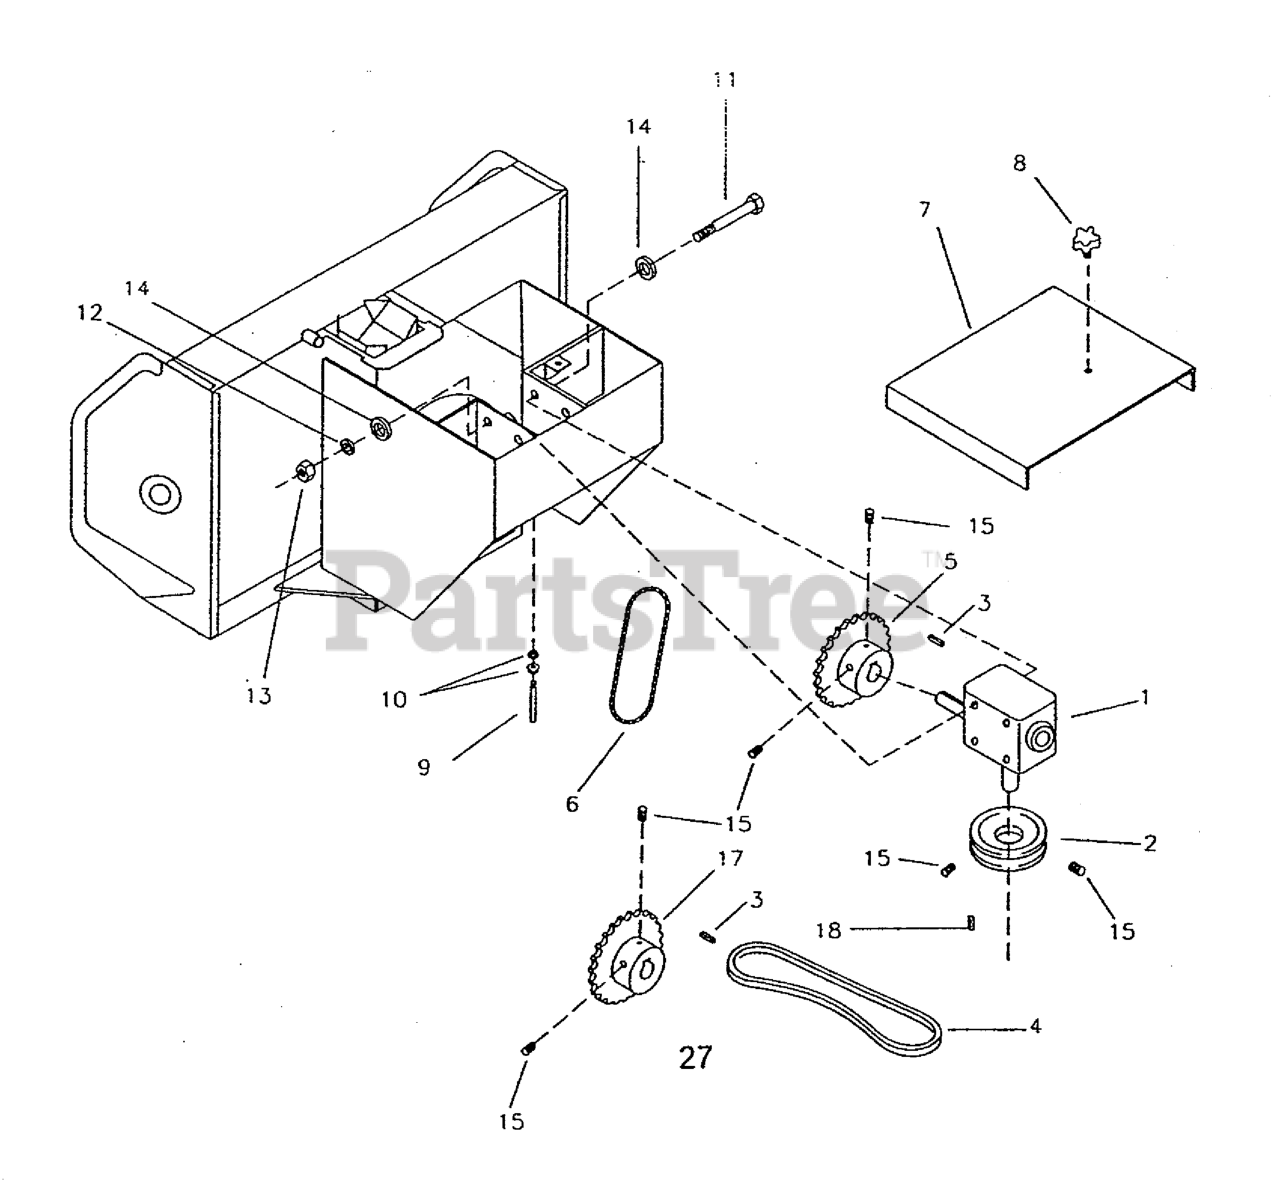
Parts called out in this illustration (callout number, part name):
1	Gear Box
2	Pulley MB 70
3	Key 1/4" x 1/4" x 1"
4	Belt (Dual Drive Models)
4	Belt (Procut 20 Models)
4	Belt (Procut 30 Models)
4	Belt (Procut S Models)
5	Sprocket 40B20
8	Knob 5/16" NC
10	Flange Nut 5/16" NC
13	Hex Nut 3/8" NC
16	Lockwasher 3/8" ext. Tooth
17	Sprocket 40B28
18	Key 1/4" x 1/4" x 1-1/4"
